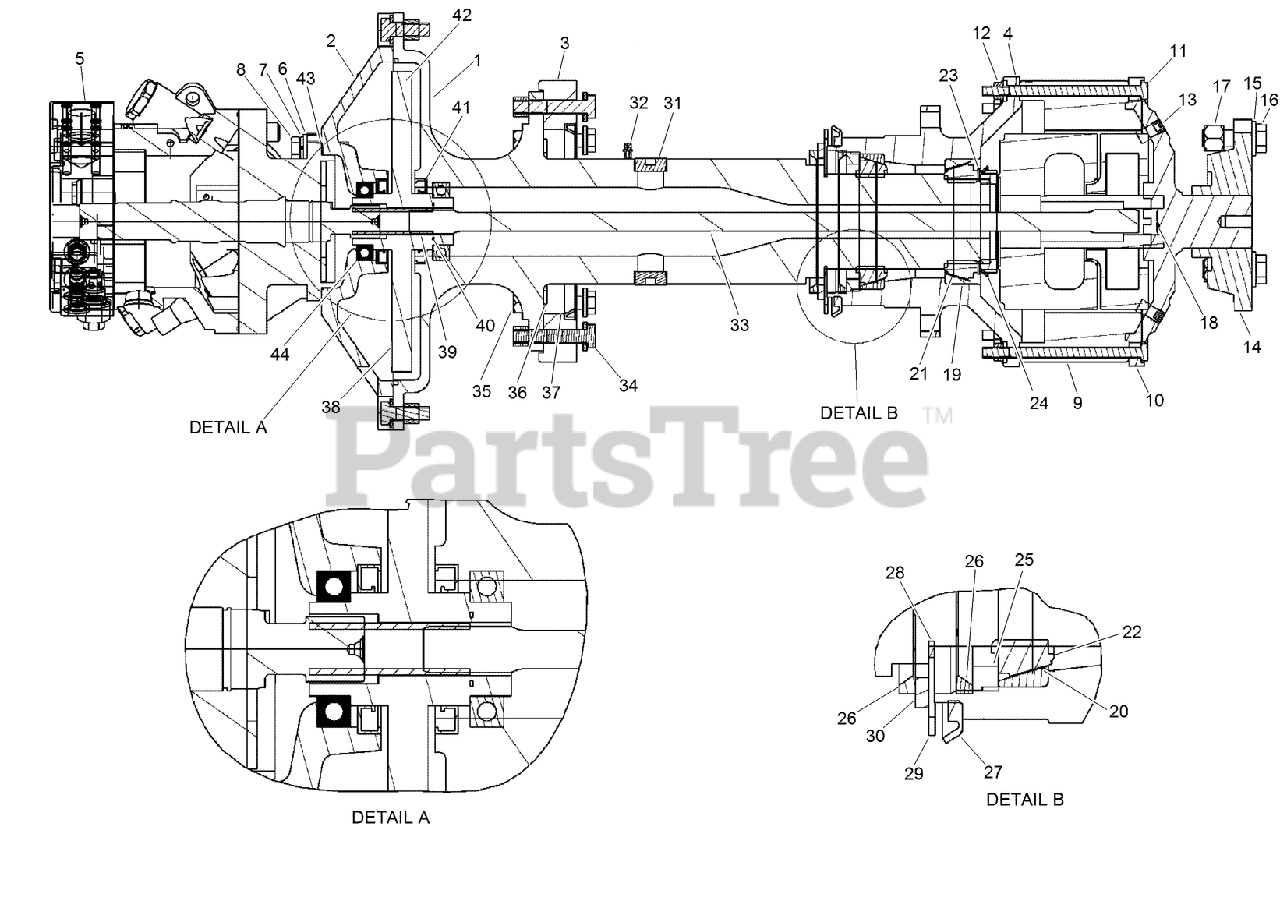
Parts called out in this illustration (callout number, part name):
1	PIVOT-BOOM
2	COVER-FLYWHEEL
3	SPACER-PIVOT, BOOM
4	HUB-SPROCKET
5	ASSEMBLY - Motor, Hydraulic, Series 90
7	WASHER-Spring Lock Reg 1/2 ZND
8	SCREW-HH
9	GEARBOX ASM
10	COVER-Planetary
12	NUT-Serr Flg 3/8-16 UNC GR5 ZND
13	PLUG-PIPE
14	BEARING
15	WASHER-FLAT
16	BOLT-Hex Hd 0.625 x 2.00 GR8 ZND
17	NUT-LOCK, HEX
18	RING-Retaining Int Basic #75 Pln
19	CUP-BEARING
20	BEARING
21	BEARING-CONE
22	BEARING
23	WASHER-Shim
24	WASHER-LOCK, BEARING
26	SEAL-Urethane
27	SEAL-PLANETARY, URETHANE
28	RING-RETAINING, EXTERNAL
29	RING-WEAR
30	WASHER-THRUST, THICK
31	PLUG-FREEZE
32	FITTING-Grease, Self Tapping
33	SHAFT-DRIVE
34	BOLT-Hex, 1/2 NC x 2-3/4 inch
35	NUT-HEX
36	WASHER-THRUST, THIN
37	SEAL-URETHANE
38	FLYWHEEL
39	BUSHING-SPLINED
40	RING-RETAINING
41	SEAL-Flywheel
44	BEARING-Ball
